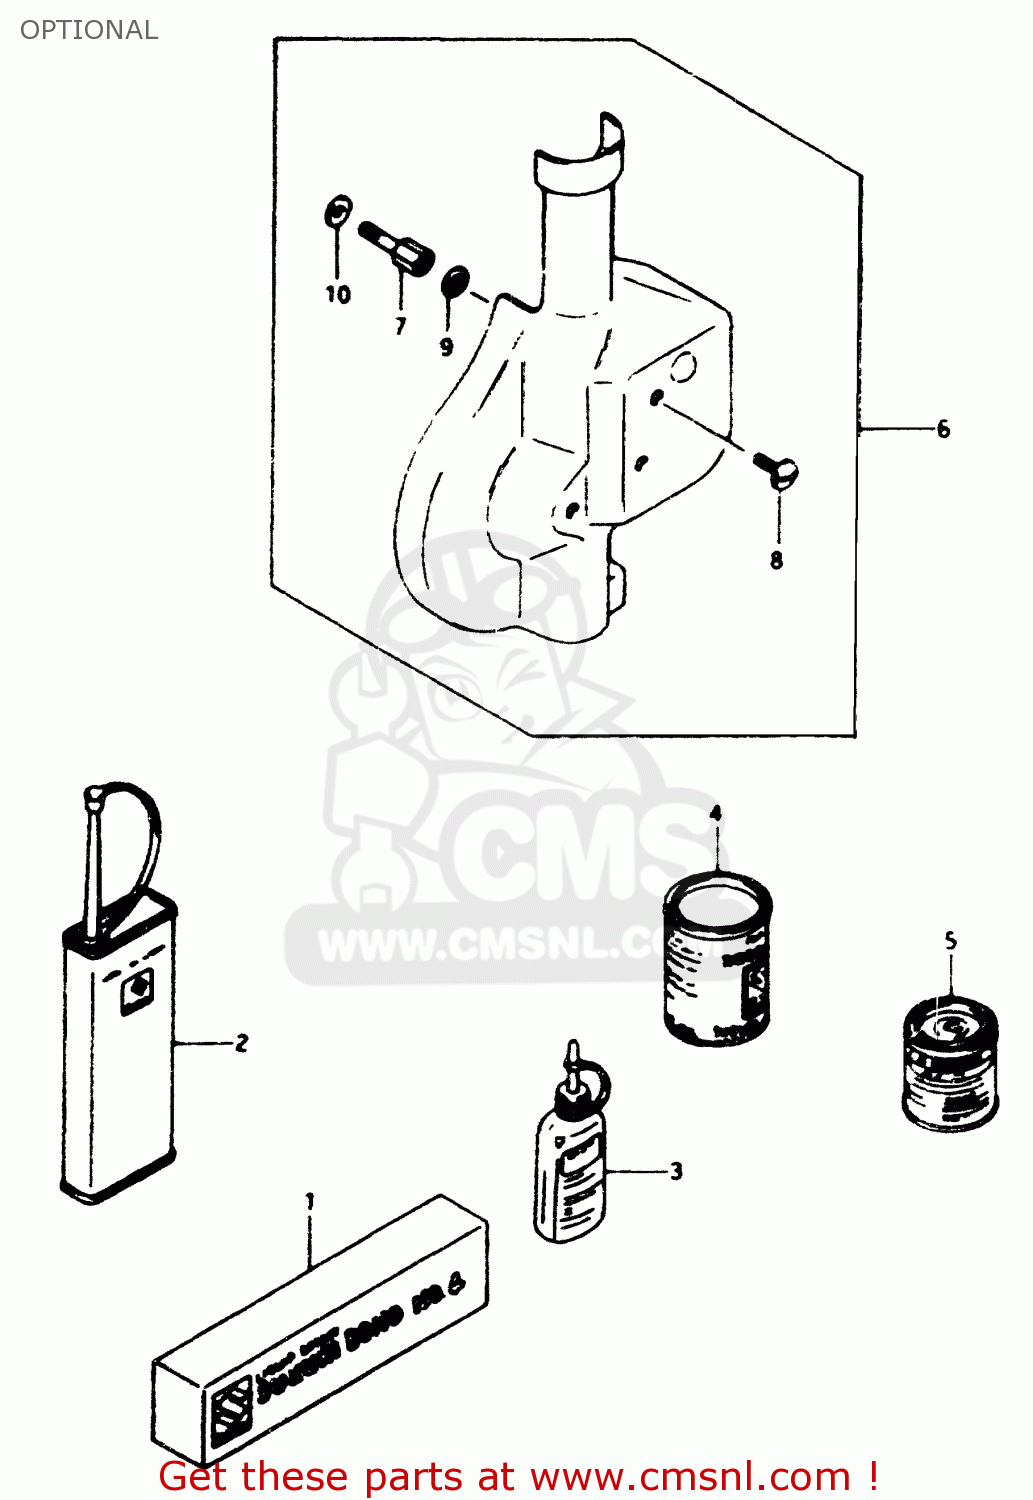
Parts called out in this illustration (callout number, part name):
1	BOND 1104
2	THREAD LOCK NO.1401 CLEAR 200G
3	THREAD LOCK SUPER(1360)
4	GREASE(C)EP2 LITHIUM 150G
5	COVER SET,FRONT DISC
6	SCREW(6X14)
7	WASHER
8	BOLT,FRONT DISC COVER
9	WASHER
